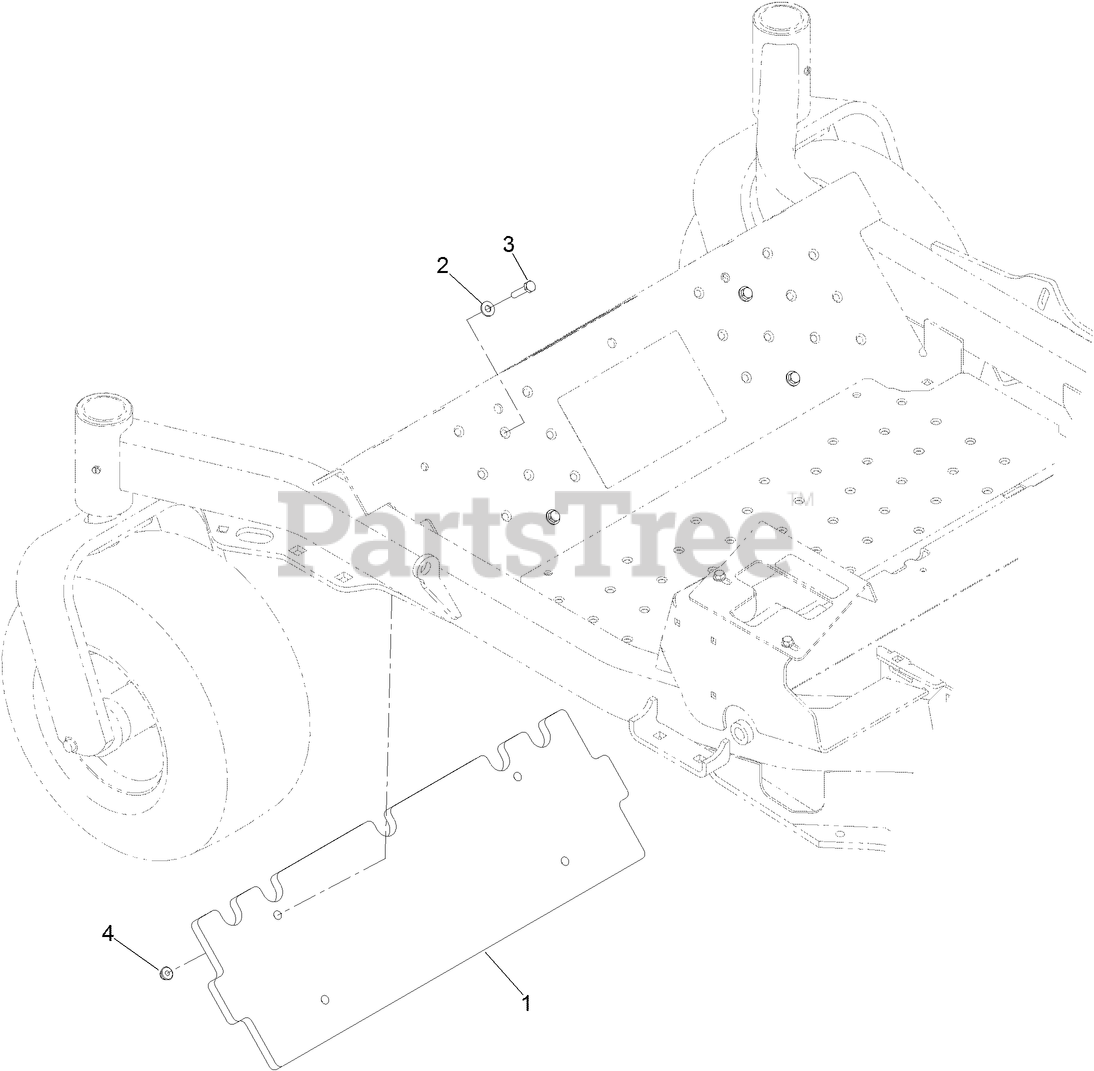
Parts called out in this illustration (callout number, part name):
1	WEIGHT-TOE BOARD
2	WASHER-FLAT
3	SCREW-HH
4	NUT-HF
